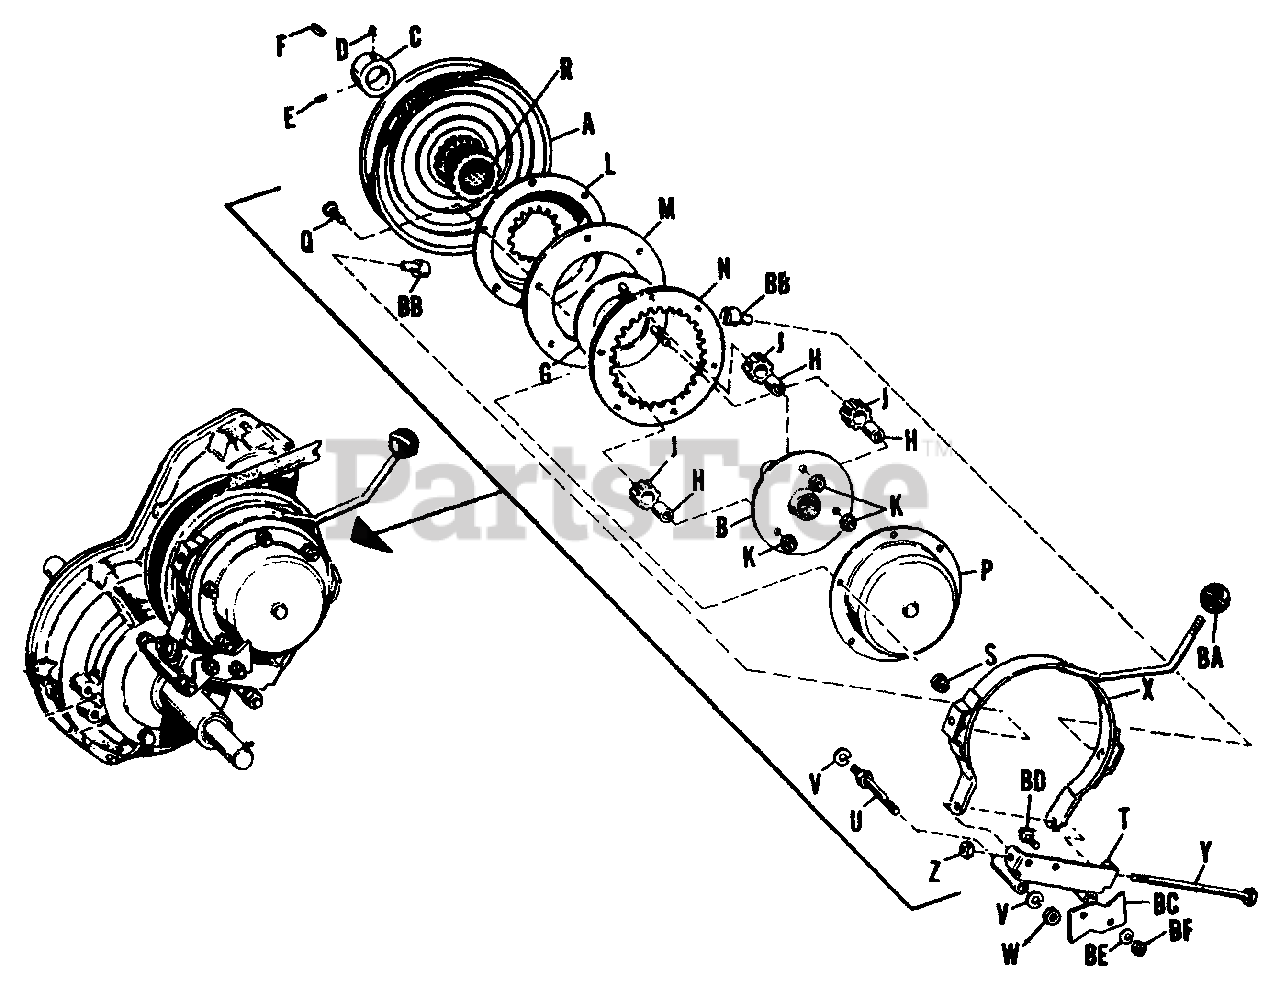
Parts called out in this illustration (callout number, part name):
A	Pulley & Gear Assembly
B	Spider & Bearing Assembly
D	Set Screws Socket Hd., CUP Pt., 5/16"-18 X 1/2"
E	Set Screw, Socket Hd., CUP Pt., 5/16"-18 X 3/8"
F	Woodruff Keys
G	Ring Assembly
K	Hex. Nut, Full 3/8"-16
L	Cover Assembly
M	Shift Ring
N	Gear Ring
P	Cover Assembley, Right Hand
Q	Hex. Capscrew, 1/4"-20 X 5/8"
R	Bushing (2 required)
S	Whiz Lock Nut Flange, 1/4"-20
T	Pivot Bracket Assembly
V	Lock Washer 3/8"
W	Hex Nut, Full 3/8"-16
X	Shift Forks Assembly
Y	Hex. Capscrew, 5/16"-18 X 6-1/2"
Z	Hex Nut, Full Lock, 5/16"-18
BB	Shift Pivot
BD	Hex. Capscrew, 5/16"-18 X 3/4"
BE	Lock Washer 5/16"
